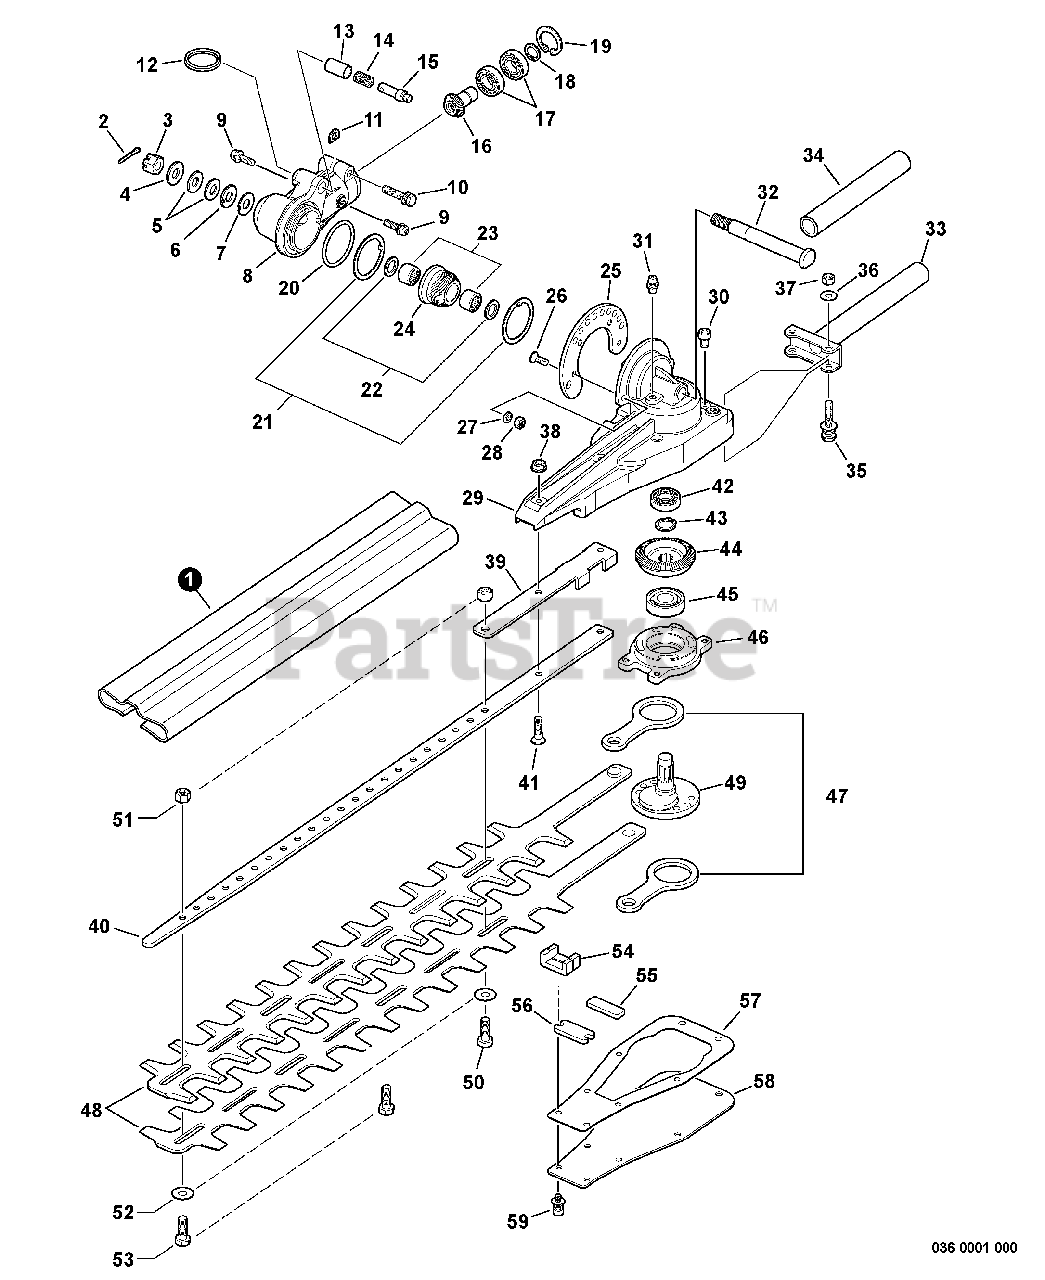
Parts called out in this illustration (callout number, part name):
1	COVER, BLADE
2	PIN, SPLIT - 6X18
4	WASHER - 8
5	WASHER - CONICAL
7	GASKET, GEAR CASE
8	CASE, GEAR
9	SCREW - 5X12
10	SCREW - 5X25
12	RING, RETAINING
13	COLLAR - 8
15	PIN - LYNCH
16	GEAR - BEVEL
17	BEARING, BALL - 6900Z
18	RING, RETAINING
19	RING, RETAINING - 22
20	O-RING - 32
22	WASHER - 10
23	BEARING, NEEDLE
24	GEAR - BEVEL
25	LATCH, RESETTER
26	SCREW - 4X12
27	LOCKWASHER - 4
28	LOCKNUT - 4
29	CASE, GEAR
30	SCREW - 5X8
31	FITTING, GREASE
32	GEAR - SHAFT
34	GRIP, HANDLE
35	BOLT - 5X28
36	WASHER - 5
37	LOCKNUT - 5
38	NUT - 5 -- FLANGE
39	GUIDE, BLADE
40	SUPPORT, BLADE
41	SCREW - 5X20
42	BEARING, BALL - 6900
43	RING, RETAINING - 11
44	GEAR - BEVEL
45	BEARING, BALL - 6001C3
46	HOLDER, BEARING
47	ROD, CONNECTING
48	BLADE, TRIMMER
50	BOLT - 6X22
51	LOCKNUT - 6
52	WASHER - 6
53	BOLT - 6X18
55	GUIDE, BLADE
56	GUIDE, BLADE
57	GASKET, GEAR CASE
58	LID, GEAR CASE
59	SCREW - 4X12
